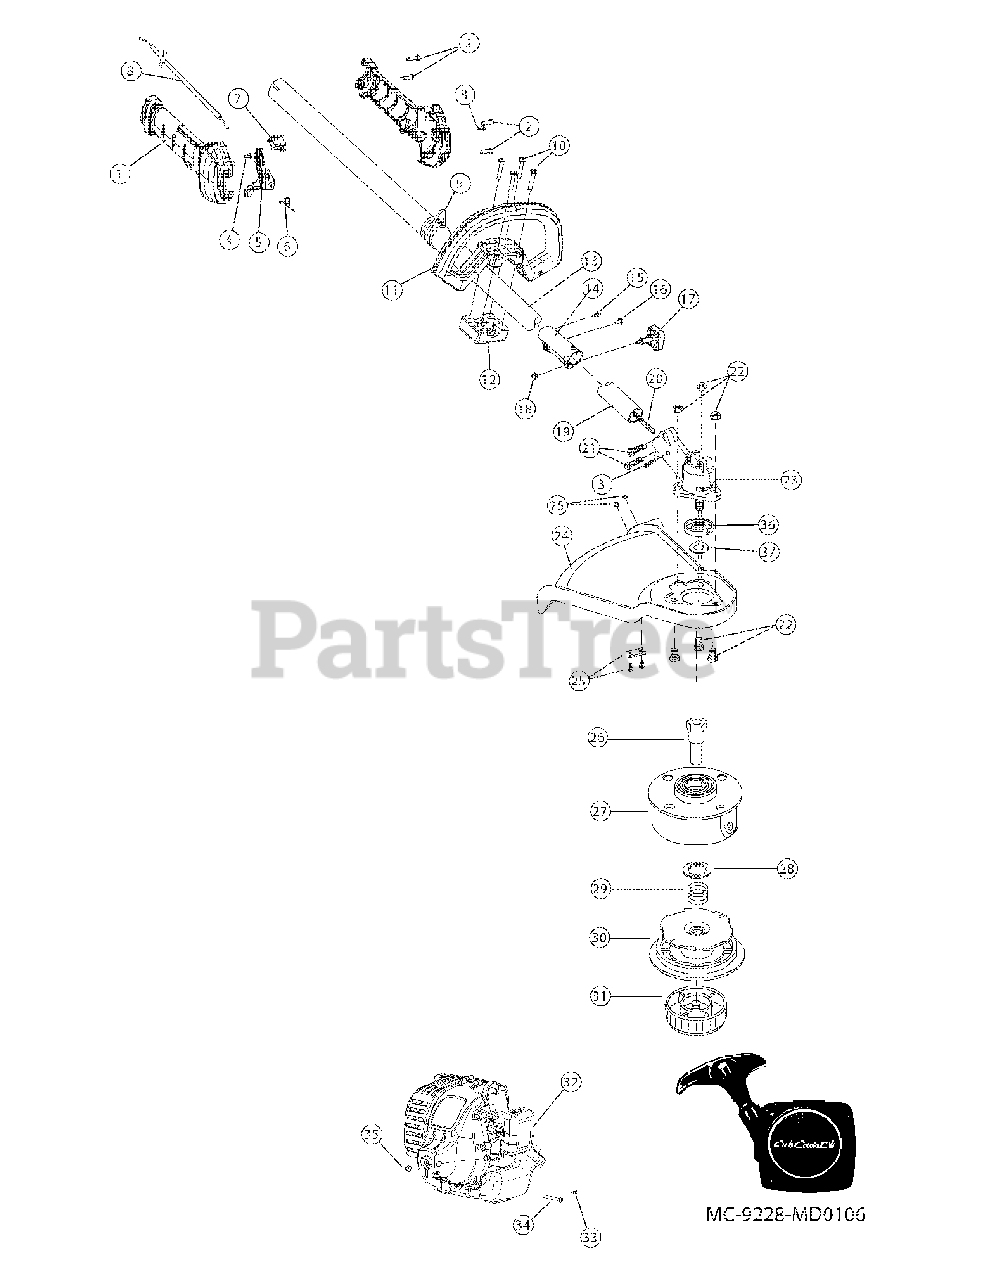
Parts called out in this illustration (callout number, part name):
1	Throttle Grip Assembly (Incl. 2-7)
3	Anti-R otation Screw
4	Throttle Cable Mounting Screw
5	Throttle Trigger
6	Throttle Trigger Spring
8	Throttle Cable
9	Harness Clip
12	D-Handle Base
13	Upper Drive Shaft Assembly
14	Split Boom Coupler Assembly (Incl. 15-18)
17	Knob (Incl. 18)
19	Lower Drive Shaft Housing Assembly
20	Lower Flex Shaft
21	Gearbox Mounting Hardware
22	Shield Mounting Hardware
23	Gearbox Assembly (Incl. 13, 21, 36 & 37)
24	Shield Assembly (Incl. 25)
25	Blade Assembly
26	Spool Shaft
27	Outer Spool Assembly (Incl. 28)
28	Retainer
31	Bump Head Knob Assembly
32	Engine Assembly
33	Anti-Rotation Screw
34	Clamping Screw
36	Gearbox Spacer
